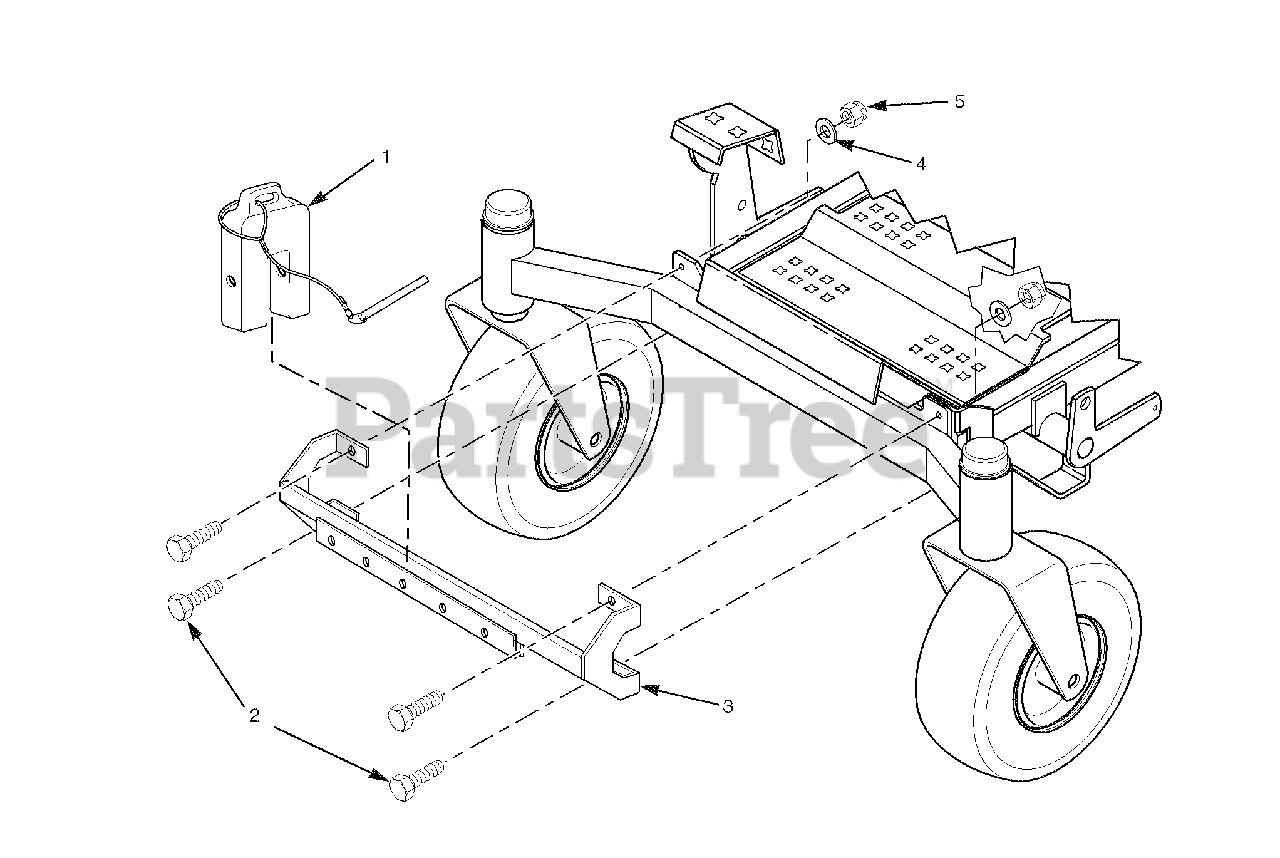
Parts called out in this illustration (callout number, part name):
1	Weight Assembly
2	Bolt, Hex Head 7/16-14 x 1-3/4"
3	Support Weldment, Weights
4	Flatwasher, 7/16-.500 x 1-1/4"
5	Nut, Elastic Stop 7/16-14
